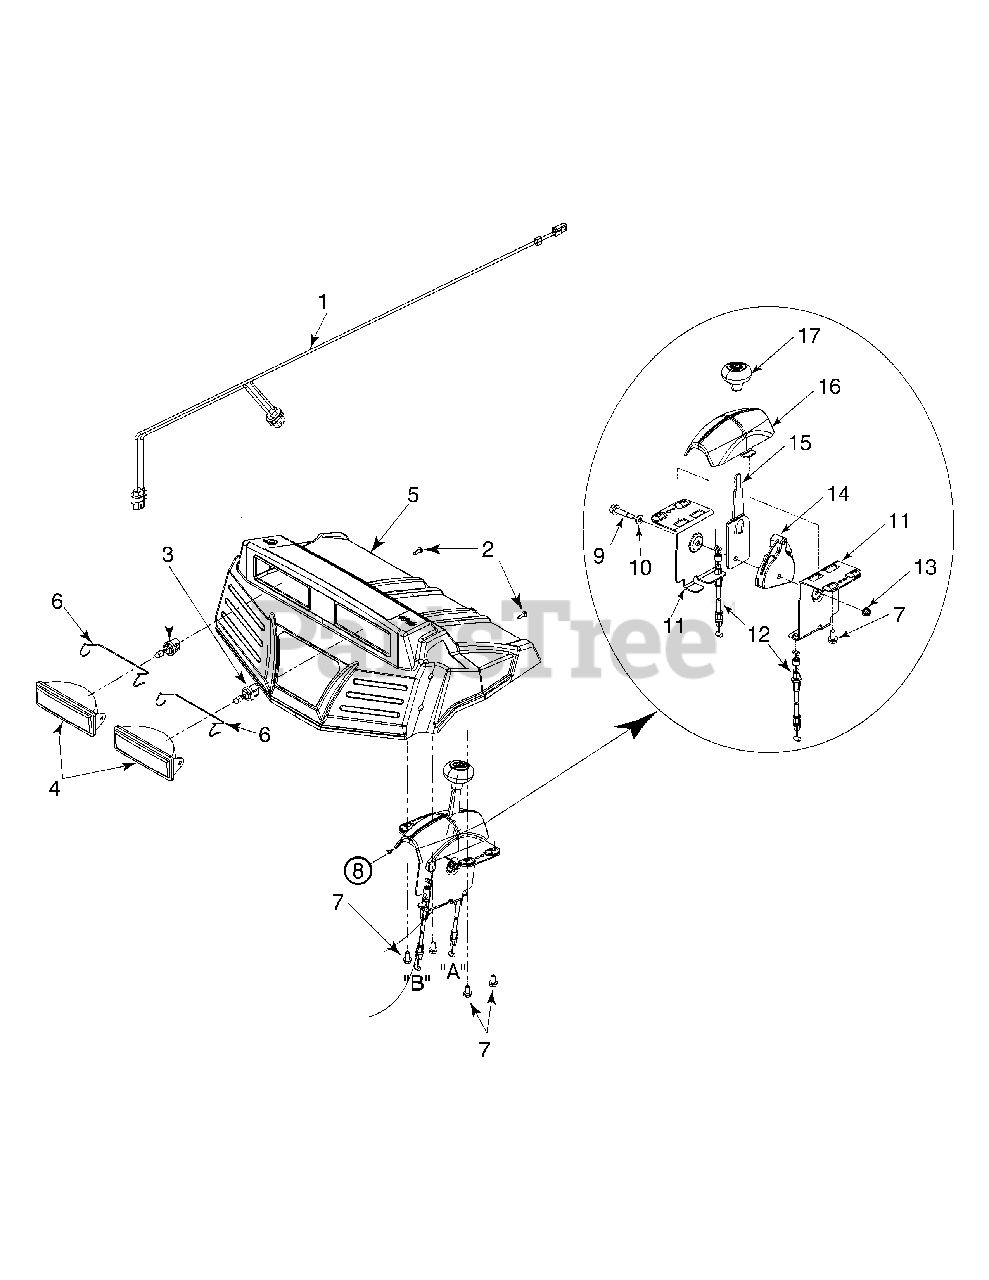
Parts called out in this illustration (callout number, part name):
2	Hex Tapp Wash Hd. Scr. #10 x 5/8
3	Bulb #890, 12 V, 27 Watt
4	Head light Housing
5	Black Handle Panel
7	Hi-Lo Screw 1/4-15 x .5
8	2 Way Chute Control Assembly
9	Flg Shlder Sscrew .310 x .995: 1/4-20
10	Spring Washer .390 x .625 x .012
11	Mounting Bracket - 2 Way
12	Cable - w/standard chute
13	Hex L-Flanged Nut 1/4-20 Gr. F Nylon
16	Control Cover - 2 Way
